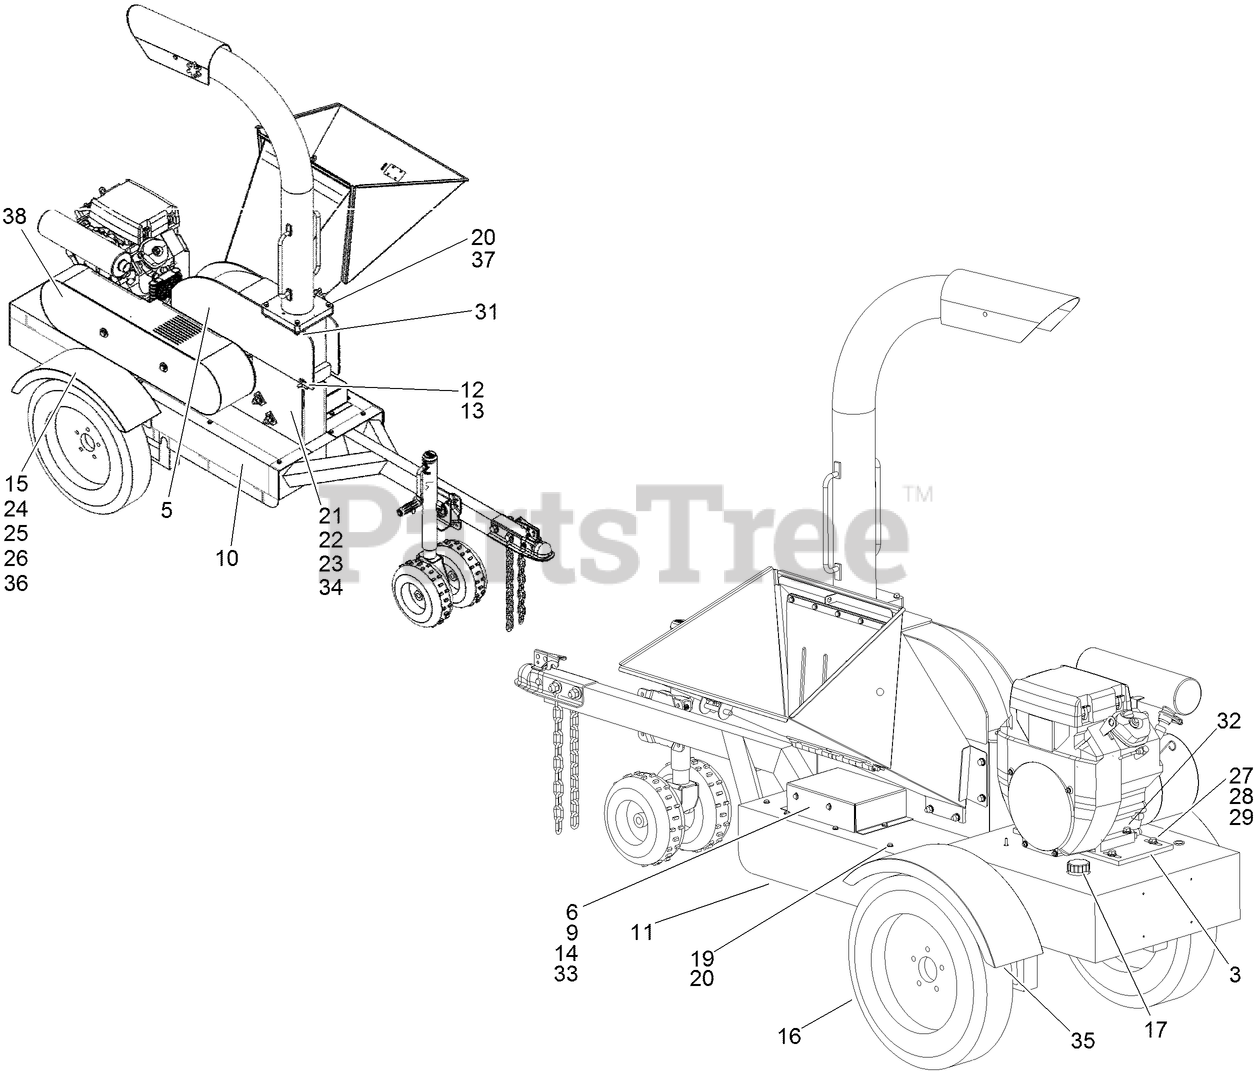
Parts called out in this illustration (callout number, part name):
3	PLATE-ENGINE
5	CHASSIS COVER ASM
6	BATTERY COMPARTMENT ASM
9	BATTERY
10	BRACKET-BODY, SMALL
11	BRACKET-BODY, LARGE
12	PIN-HINGE
13	PIN-COTTER
14	PLATE-COVER, BATTERY
15	WASHER-PLAIN
16	WHEEL AND TIRE ASM
17	CAP-GAS
19	SCREW-HWH
20	WASHER-FLAT
21	SCREW-HH
22	WASHER-FLAT
23	WASHER-LOCK
24	WASHER-FLAT
25	WASHER-LOCK
26	SCREW-HH
27	WASHER-FLAT
28	WASHER-LOCK
29	SCREW-HH
31	NUT-HEX
32	SCREW-HH
33	BRACKET-BATTERY
34	SWITCH-PLUNGER, NC (W/COVER)
35	LEFT FENDER ASM
36	RIGHT FENDER ASM
37	SCREW-HH
38	BELT-V, CHIPPER
